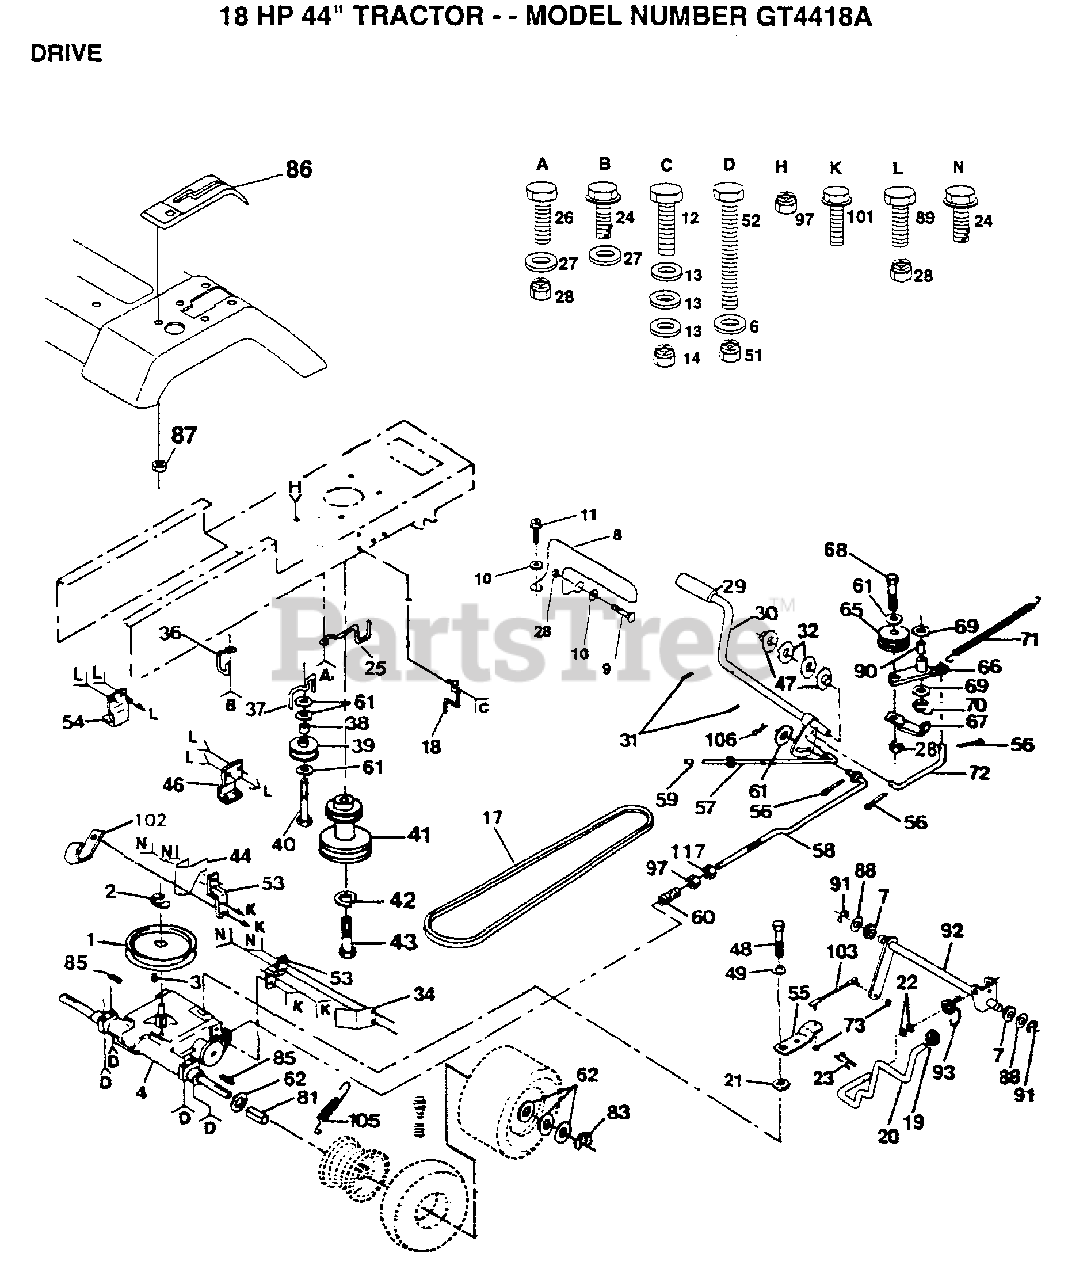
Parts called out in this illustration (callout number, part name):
1	PULLEY TRANSAXLE
2	RING
4	TRANSAX. PRLES.
6	WASHER M
7	BUSHING
8	MUFFLER GUARD
9	BOLT D
10	WASHER HYT
11	SCREW GTV
13	WASHER
14	NUT
17	BELT.GRDRV.94.75
18	KEEPER BELT ENG
19	KNOB T (1/2-HOLE)
21	WASH-SHFT PLT LT
22	WASHER
23	PIN COTTER 1/8
24	SCREW
25	KEEPER.BELT.ENG.L
26	BOLT
27	WASHER
29	PEDAL COVER T
32	WASHER LT
34	"KEEPER,BELT RH"
36	KEEPER BELT CNTSP
37	BELT KEEPER LT
38	SPACER T
39	PULLEY.IDLER.FLAT
40	BOLT
41	PULLEY.ENGINE
42	LOCKWASHER
43	BOLT
44	KEEPER BELT LH
46	BRKT TRANS RH
47	NYLON BEARING
49	WASHER PM
51	NUT
52	BOLT HEX
53	STRAP TORQUE
54	BRKT TRANS LH
55	"ARM,SHIFT"
56	COTTER PIN
57	BRAKE PARK ROD
58	ROD BRAKE
59	PLUNGER CAP T
60	"SPRING,ROD BRAKE"
61	WASHER
62	WASHER
66	ARM IDLER
67	RETAIN BELT
69	WASHER LT
70	KLIP RING
71	"SPRING, RETURN LT"
72	"LINK, CLUTCH T"
73	NUT 1/4-28
81	SPACER HYT
83	E RING HYT
85	SQ KEY STD
86	CONSOLE SHIFTER
87	NUT
88	WASHER D
90	"LY, BEARING"
91	KLIP RING
92	"SHAFT,SHIFTER"
93	"SPRING,TORSION"
97	NUT
101	SCREW
102	CLIP T
103	"ROD,TIE "
106	RETAINER M
117	NUT
